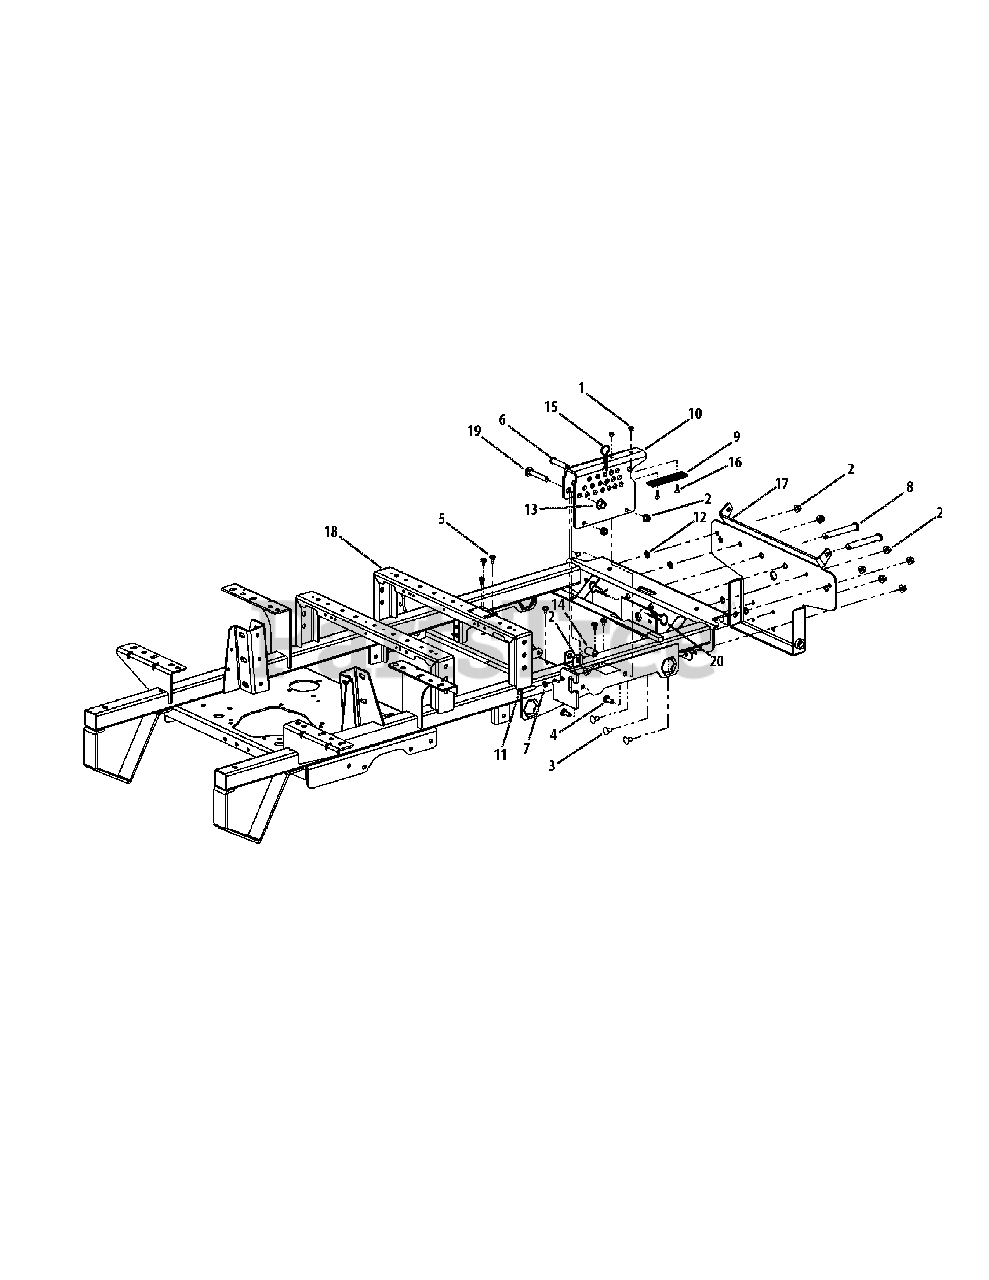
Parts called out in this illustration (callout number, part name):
1	Lock Nut w/Nylon Insert
2	Hex Nut, 3/8-16 Flange Lock
3	Carriage Bolt, 3/8-16 x .75 Long
4	Carriage Bolt, 3/8-16 x 1
5	Rubber Bumper, .62 OD x .22 Thick
6	Clevis Pin, .500 Dia. x 2.50 Lg.
7	Nut, 3/8-16, Jam
8	Clevis Pin, .625 Dia x 4.375 Long
9	Wear Plate, 1.25 x 5.00
10	Lift Index Bracket
11	Hex Cap Screw 3/8-16 x 2.00
12	Push Retainer, 3/8
13	Nut, 1/2-13, Flangelock
14	Spacer, .51 ID x .75 OD x 1.40
15	HitchPin, .120 Dia. x 3.0
16	Flat Head Cap Screw, 1/4-20 x .75
17	Bracket Assembly, Frame, Front
17	Bracket Assembly, Frame, Front, 72"
18	Frame Assembly
19	Carriage Bolt, 1/2-13 x 3.00
20	Linch Pin, 3/16 Dia. (37HP Kawa, 72")
